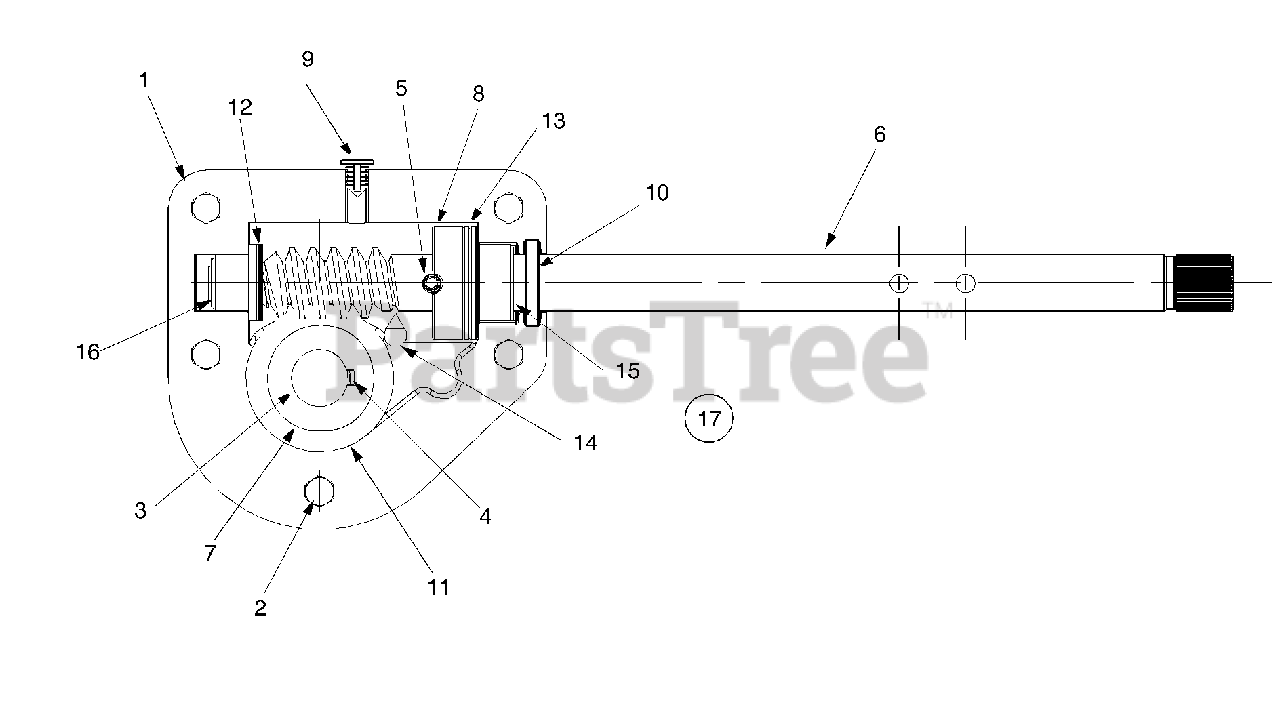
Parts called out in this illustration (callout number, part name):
1	Housing-R.H.
2	Hex Screw 1/4-20 x .75
3	Spiral Axle 26"
4	Key
5	Pin-Spiral
6	Shaft-Worm
7	Gear-Worm
8	Collar-Thrust
10	Seal-Oil
11	Washer-Flat
12	Washer-Flat
13	Washer-Flat
14	Grease
15	Bearing-Flange
16	Bearing-Flange
17	Ass'y. Complete 26"
